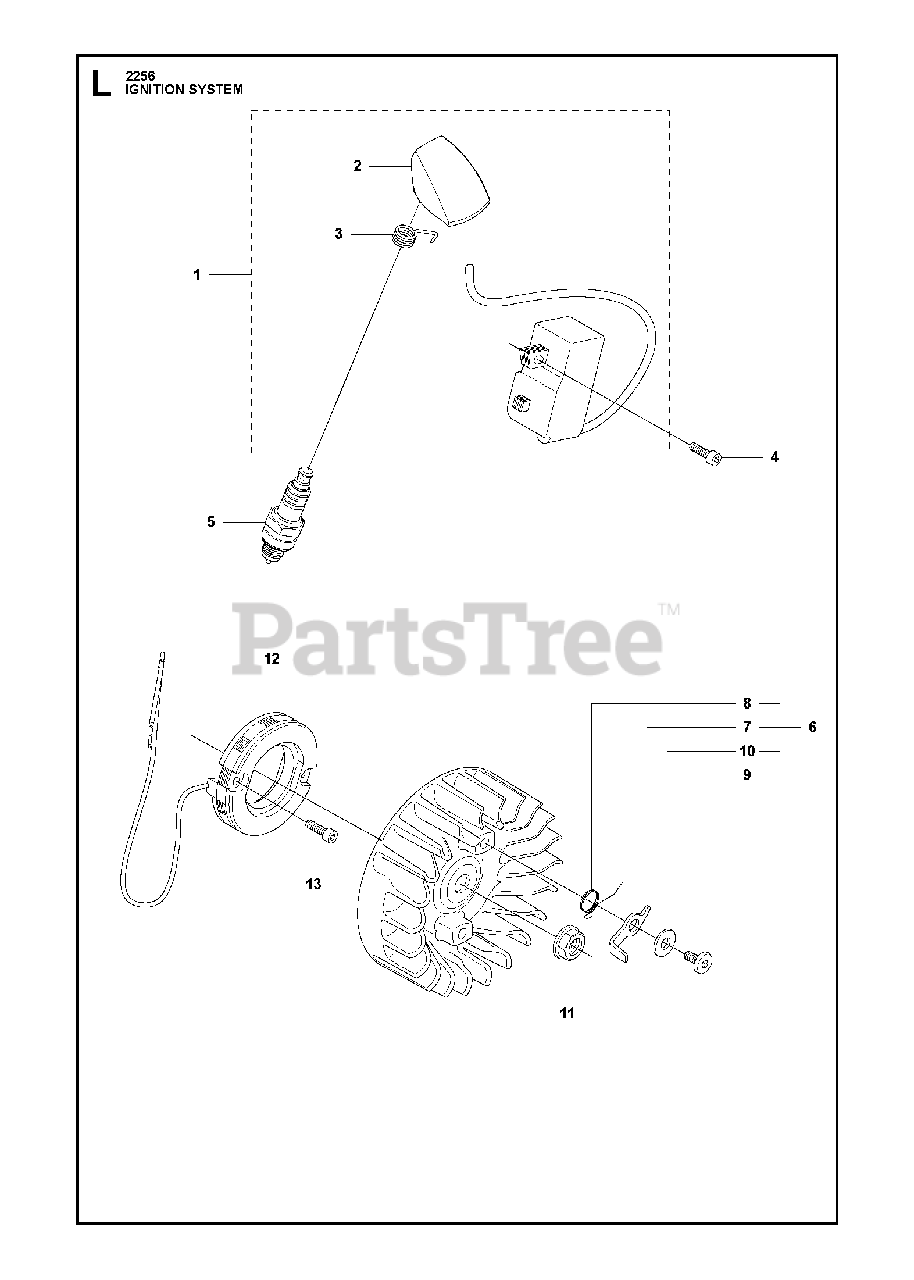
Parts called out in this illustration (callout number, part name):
1	RP IGNITION MODULE
3	SPRING
5	BPMR7A NGK SPARK PLUG
6	FLYWHEEL ASSY
7	STARTER PAWL
8	SPRING
9	PIN, STARTER CATCH
10	WASHER
11	NUT W/ WASHER
12	GENERATOR STARTER
13	SCREW
